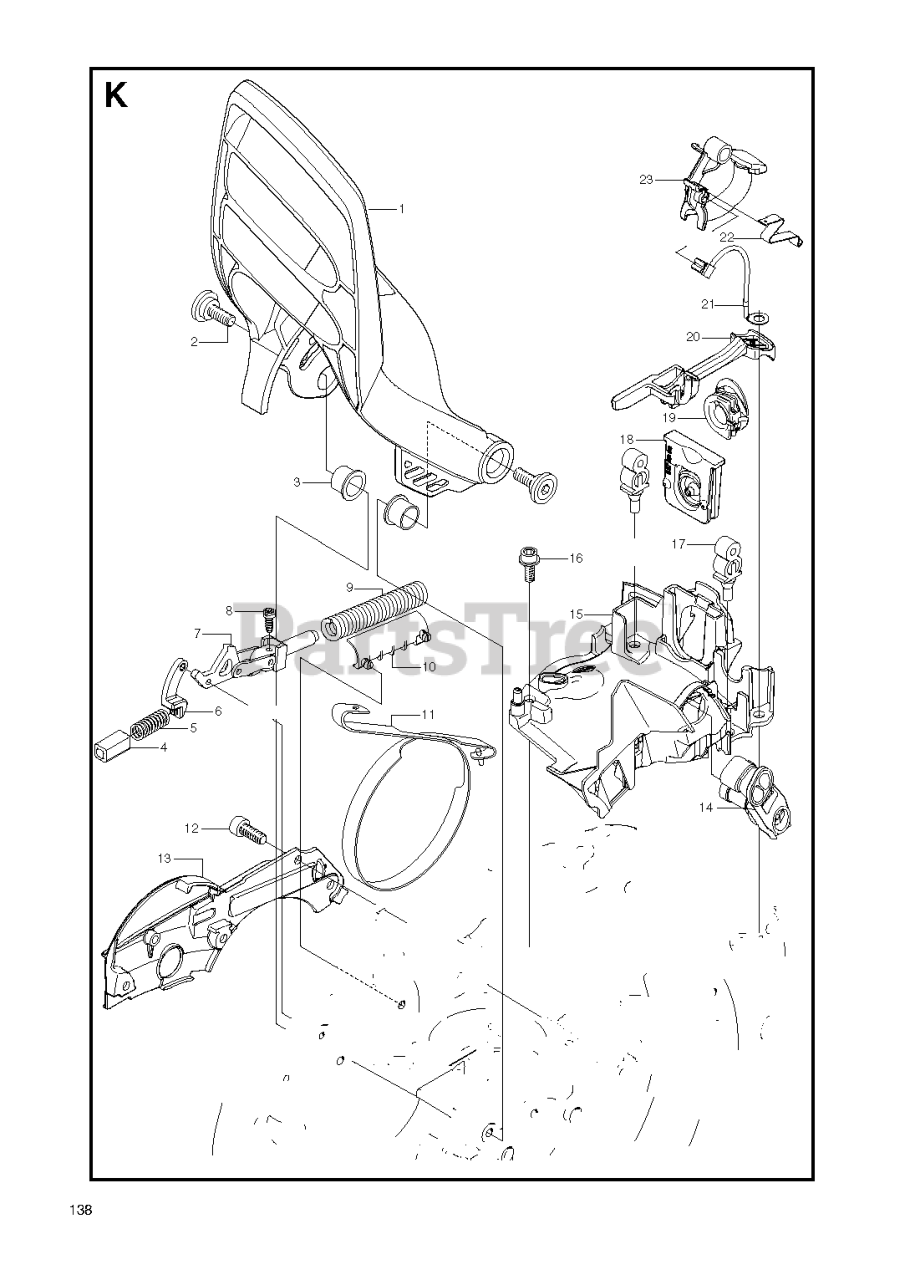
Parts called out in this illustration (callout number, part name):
1	HAND GUARD
5	LOCK SPRING
7	KNEE JOINT
9	BRAKE SPRING
10	%SUPPORT
11	BRAKE BAND
15	CARBURETOR AREA BAS G
17	SUPPORT
20	CHOKE CONTROL
23	STOP CONTROL
